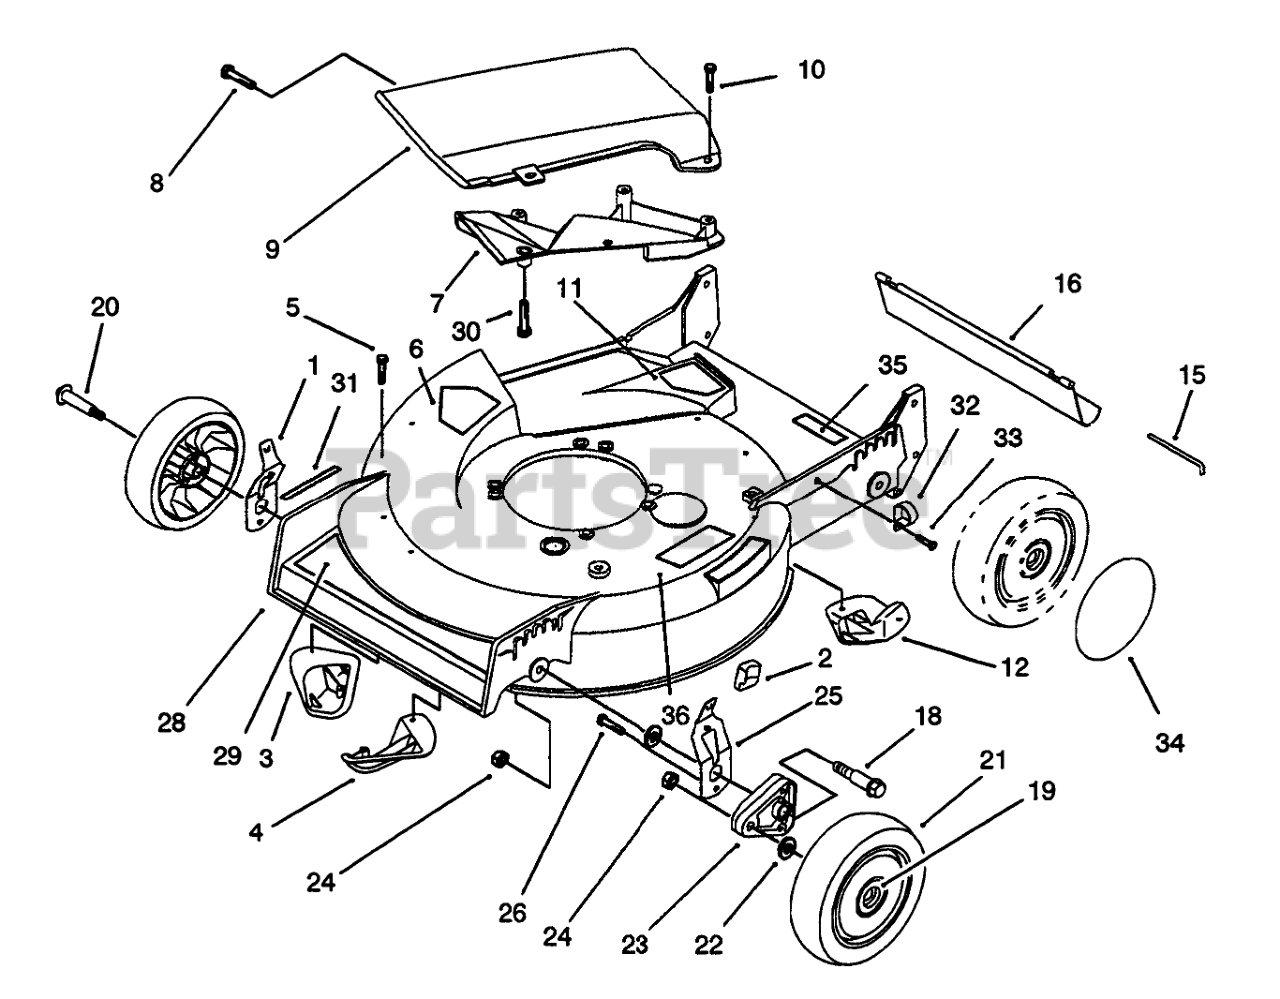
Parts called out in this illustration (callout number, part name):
1	RH SPRING ARM ASSEMBLY
2	KNOB-ARM
3	KICKER-RH
4	KICKER-FRONT
5	SCREW-PPH
6	DECAL-DANGER
7	Deflector-Recycler
8	SCREW AND WASHER ASM
9	Cover Assembly (Incl. Ref. #7 & 30)
10	SCREW-HWH
11	DECAL - DANGER
12	KICKER-REAR
15	ROD-SHIELD
16	SHIELD-TRAILING
18	BOLT-SHOULDER
19	BUSHING
20	BOLT-WHEEL
21	Wheel & Tire Assembly (Incl. Ref. #19)
22	WASHER
23	ARM-PIVOT, FRONT
24	NUT-LOCK
25	LH SPRING ARM ASSEMBLY
26	SCREW-HWH
28	Housing Assembly (Incl. Ref. #3-6, 11, 12, 31, 35, & 36)
29	DECAL - DECK
30	Screw-Pan Hd.
31	DECAL - HOC
32	CLAMP-CABLE
33	SCREW-HWH
34	WHEEL COVER
35	DECAL-WARNING
36	DECAL-INSTRUCTION, SAFETY
